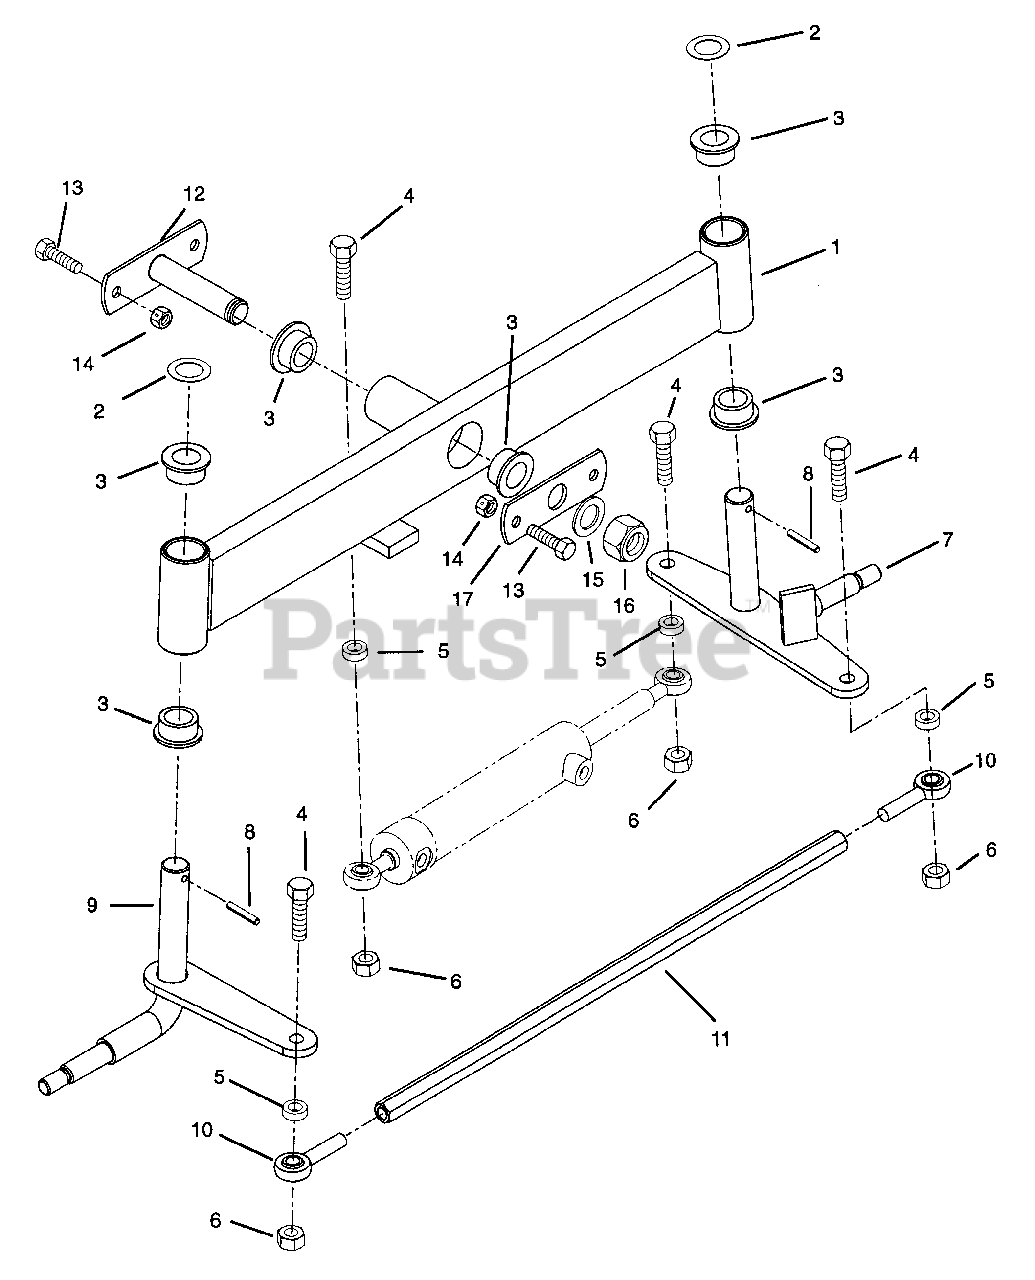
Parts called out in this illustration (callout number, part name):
1	Weldment,PM-350 Steering Axle
2	Washer-Hardened-Thrust 1.002 x 1.552 x .030
3	Bushing-Flange 1.020 x 1.385 x .75 x 1.75
4	Bolt-Hex .50-13 x 2.00 Grade 5
5	Spacer .516 x .875 x .300
6	Nut-Locking-Nylon .50-13 Grade 5
7	Weldment,King Pin Left Hand
8	Pin-Roll .250 x 1.50
9	Weldment,King Pin Right Hand
10	Assembly,Rod End
12	Weldent, Steering Axle Pin
13	Bolt-Hex .38-16 x 1.00 Grade 5
14	Nut-Locking-Center .38-16
15	Washer-Flat-Steel 1.015 x 1.500 x .125
16	Nut-Lock 1.0-14
